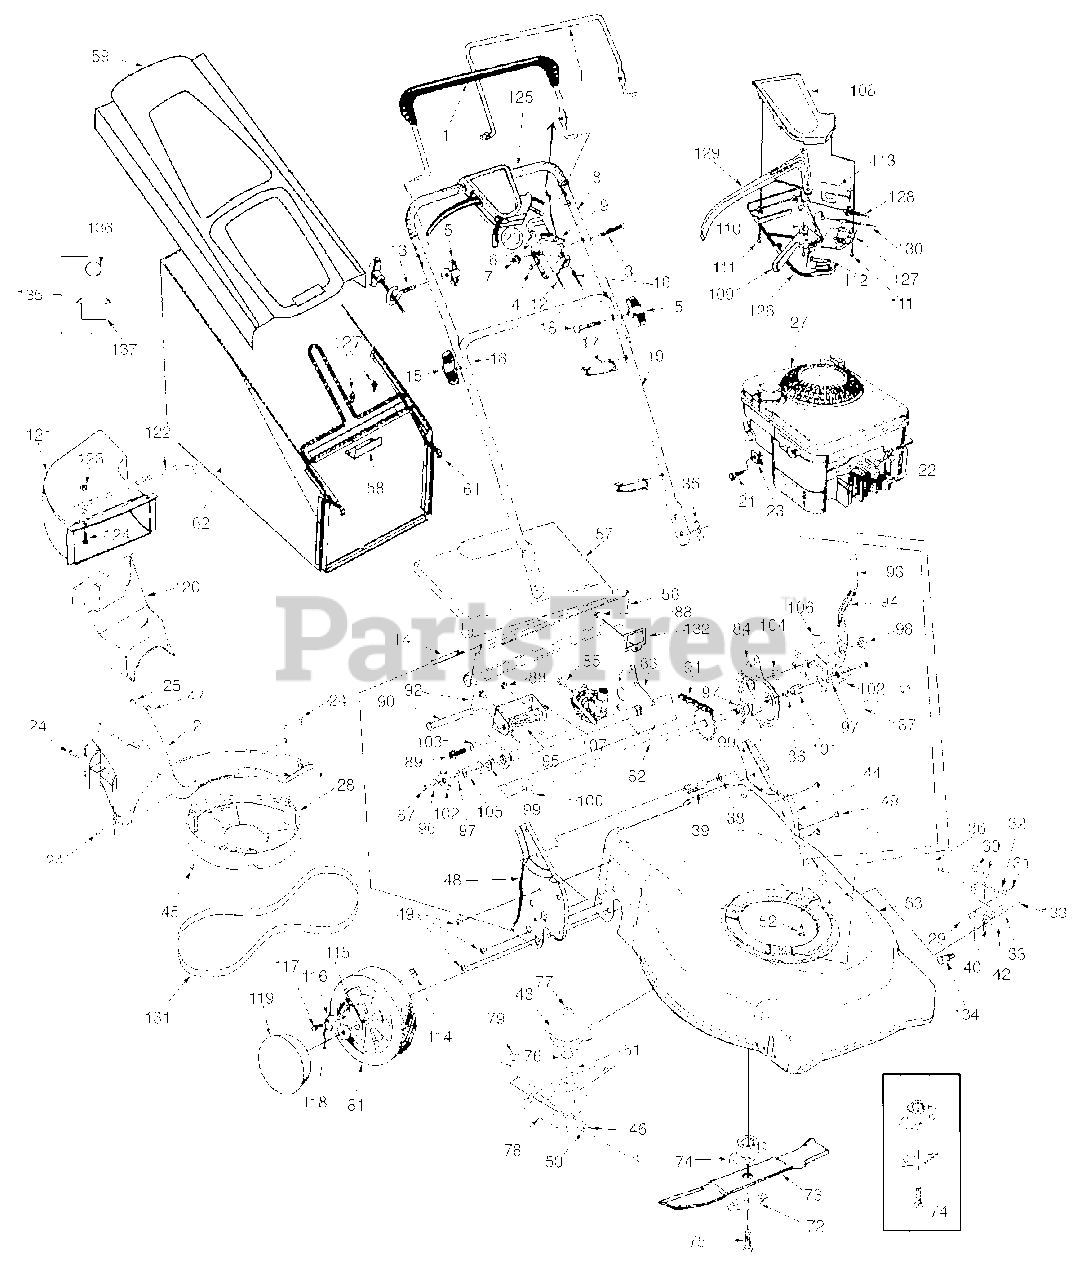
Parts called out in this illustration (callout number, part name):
2	Baffle
3	Oval C-Sunk Mach.-Scr.
4	Spr. Wash. .66" I.D.
5	Handle Knob 1/4-20 Thd.
6	Throttle Body
7	Hex L-Nut 1/4-20
9	Throttle Lever
12	Throttle Control Wire-55"
13	Rope Guide
14	Wire-47" Lg.
15	Hand Knob
16	Control Cable-40.5"
17	Cable Tie
18	Curved Hd. Bolt 5/16-18 x 2" Lg.
20	Throttle Box Comp.
21	Hex Self-Tap Scr. #10-32 x .62" Lg. (B&S)
22	Spark Plug Boot
23	Cable Clamp (B&S)
24	Screw H.L. 12-24
25	Screw Mach. B Tapp.
27	Engine
28	Belt Cover
29	Scr. 1/4-20: .50 Lg.
30	Scr.:AB 1/4-20: .625 Lg.
31	Hex Nut: 1/4-20
32	Bell Wash. .265 x .75 x .062
33	Lock Wash. 1/4
35	Int. Cotter Pin 5/15" Dia.
37	Pivot Rod
38	Shoulder Spacer
39	Torsion Spring L.H.
40	Roller Cable
46	Pivot Shaft
47	U-Nut
50	Torsion Spring
51	Wv. Wash. 1.38 O.D. x .88 I.D: .029
52	Hx L-Wash Hd. Scr. 3/8-16 : 1" Lg.
62	Grass Bag - Black
72	Blade Bell Support
73	21" Mulching Blade w/Star
74	Blade Adaptor Kit w/Star
75	Hex Bolt 3/8-24 x 2.5 Lg.
76	Spacer - Sleeve
77	Spacer - Sleeve
81	Wheel Assembly
82	Axle Ass'y: RR
86	Scr. TT 1/4-20
87	Hx Cap Screw 1/4-20
88	Scr. AB 1/4-20
89	Scr 3/8-16 x 1.25
90	Pin - Clv. .500 Dia. x .4.62 Lg.
91	Chain: Endless 48: .500P x 22L
92	Pin - Cotter .125 O.D. x .75
93	Grip - Foam
94	Spring Lever
95	Torsn Spring
96	Bell Washer .265 x .75 x .062
97	Wash. - Fl .508 I.D. x 1.0 O.D. x.020
98	Nut - Shoulder .625 x .165 Lg.
99	Bearing - Flg Hex
100	Bearing - Flg. Hex
101	Bearing - Sleeve
102	Rachet Wheel
103	Spacer - .385 x .625 x .700
104	Spacer - Shoulder .385 I.D. x .715 Lg.
105	Spacer Sleeve .520 I.D. x .950 Lg.
106	Pivot Arm
109	6 Speed Shift Lever
110	Gear Insert
111	C-Sunk Tap Scr. #10 x .75" Lg.
112	Shift Lever Spring
113	6 Sp. Rack Cable Bracket
114	Weld Top L. 1/4-20
115	Pawl Plate
116	Pawl R.H.
117	Shldr Scr. .340 x .285
118	Spring, Rachet
119	Hub Cap
120	Mulch Plug
121	Chute Deflector
122	Chute Mounting Rod
123	Hex-L-Nut 1/4-20 thd.
124	Mach. Scr. 1/4-20
125	Foam Grip
126	Lower Control Housing
127	Cable Mounting Cap
128	S.P. Cable
129	Control Lever
130	6 Speed Cable - 53" Lg.
131	Belt
134	Sh. Scr. 1/4-28: .375 Lg.
135	Flo Indicator Ass'y
136	Flo Indicator Ball
137	Flo Indicator Housing
